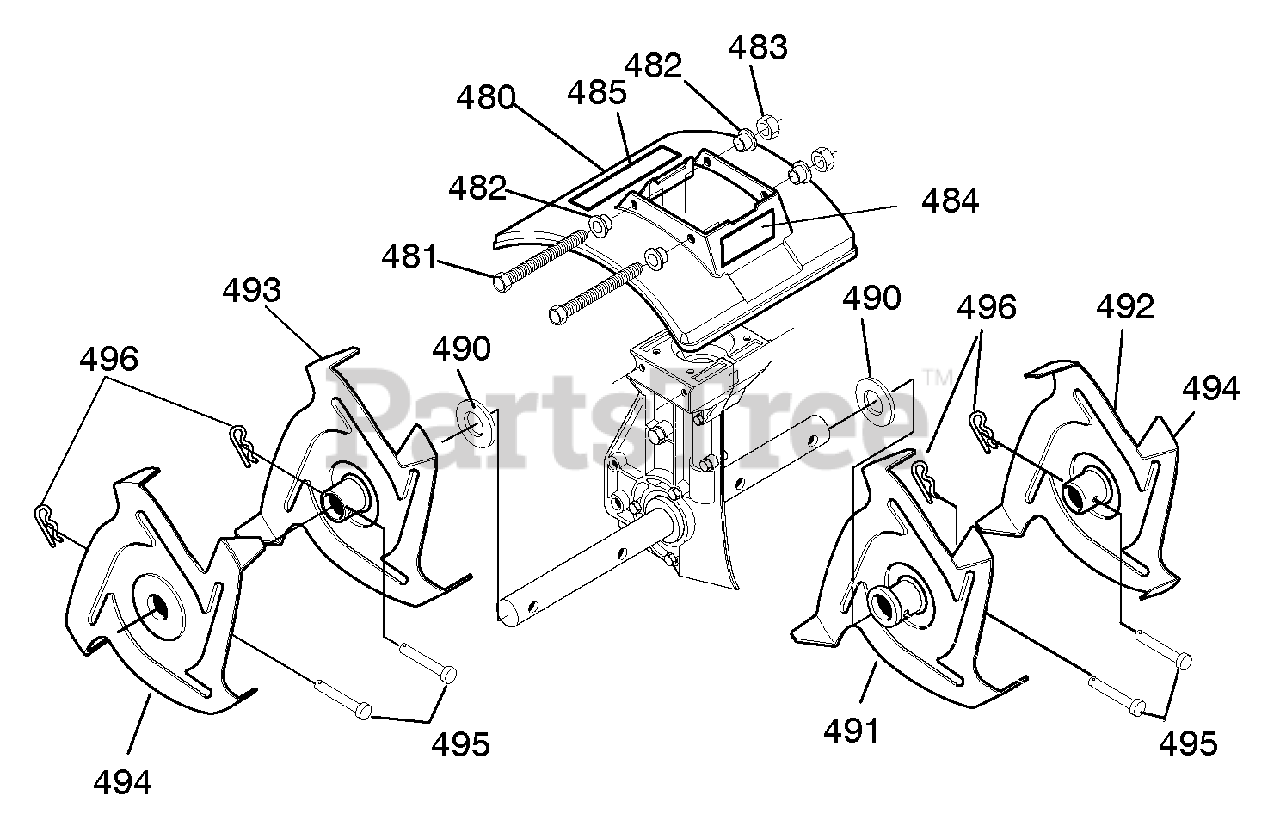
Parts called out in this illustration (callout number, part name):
480	Shield, Tine
481	Screw, 1/4-20x5.50
482	Spacer, Flange
483	Nut, 1/4-20
484	Decal, Murray
485	Decal, Caution
490	Washer, Felt
491	Tine Assy. Inner LH
492	Tine Assy. Outer LH
493	Tine Assy. Inner RH
494	Tine Assy. Outer RH
495	Clevis Pin
496	Hair Pin
